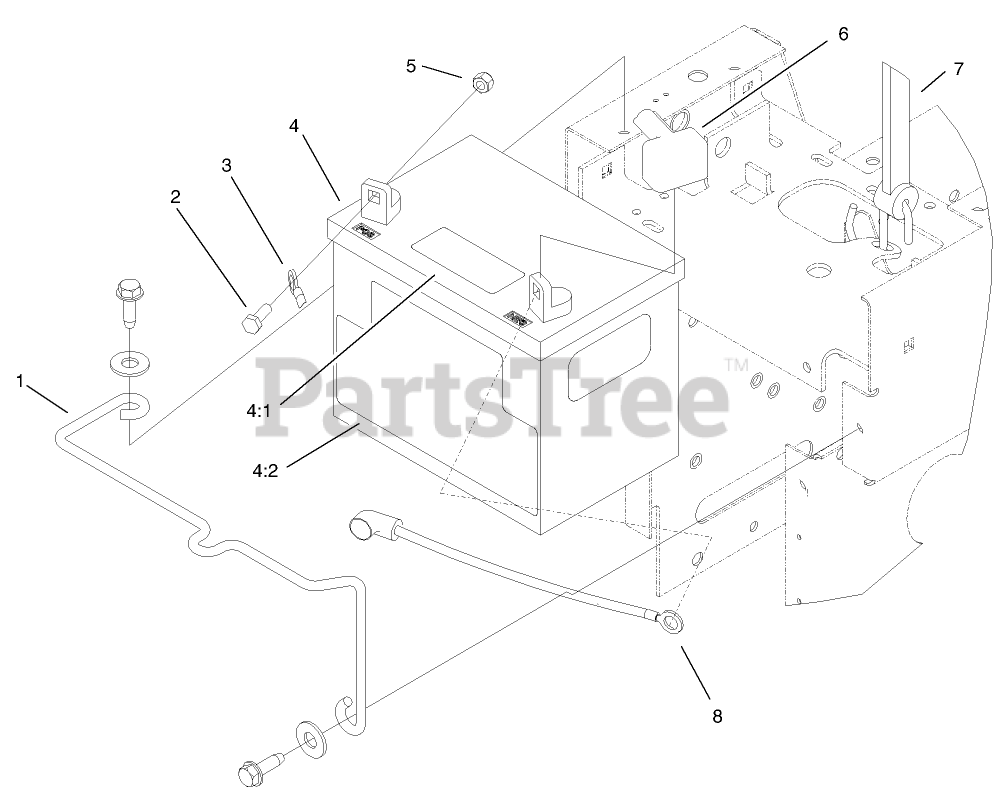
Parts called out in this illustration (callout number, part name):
1	ROD-BATTERY
2	SCREW-HH
3	CABLE-NEGATIVE, BLACK
4:1	Decal-Battery
4:2	Decal-Battery
5	NUT-LOCK, NI
6	BOOT-TERMINAL
7	HOLDDOWN-BATTERY
8	CABLE-BATTERY, POSITIVE
